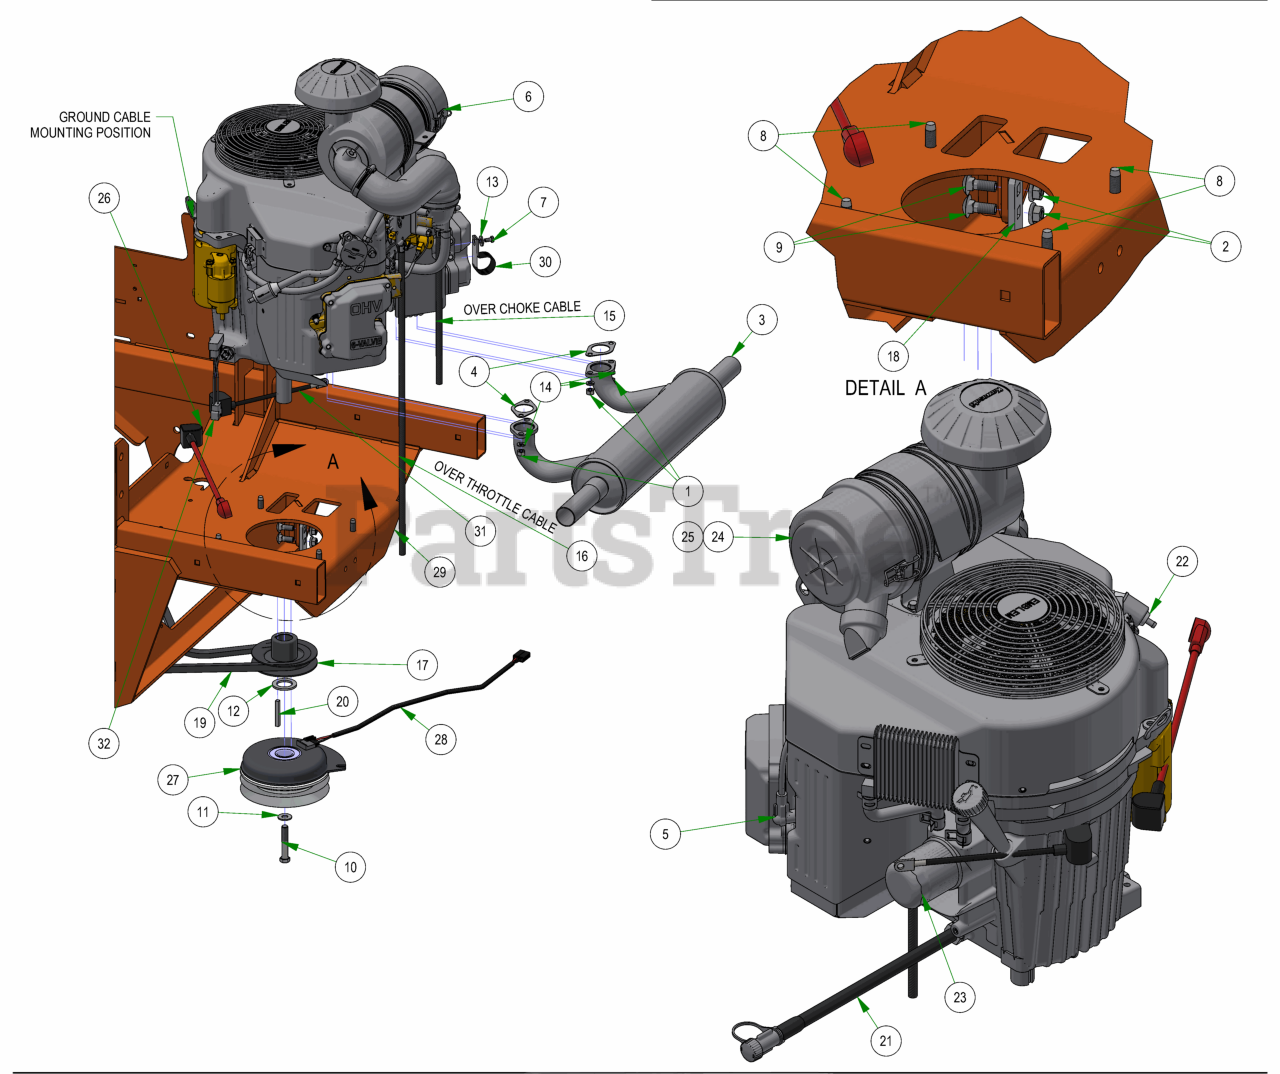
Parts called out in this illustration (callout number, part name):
1	M8-1.25 DIN 934 HEX NUT (CL.8) ZINC
2	3/8-16 NYLON INSERT FLANGE LOCKNUT (GR.F) ZINC
3	2019 Rebel/Rogue Kawasaki 1000 Muffler
4	Exhaust Gasket
5	Spark Plug - Kawasaki
6	Kawasaki FX1000 Engine
7	M6-1.0 X 12MM DIN 933 HEX TAP BOLT (CL 8.8) ZINC
8	3/8-16 X 1-1/8 HEX WASHER UNSLOT SERRATED (TRI-LOB) TRS ZINC YELLOW
9	3/8-16 X 1 CARRIAGE BOLT (GR.5) ZINC
10	7/16-20 X 2-1/2 HEX Bolt GR 8 W/ Patch
11	3/8 FLAT WASHER USS (1" OD) ZINC
12	1.140 ID X 1.750 OD X .132 THICK FLAT WASHER PLAIN
13	1/4 USS FLAT WASHER (3/4 OD) ZINC
14	5/16 SPLIT LOCKWASHER ZINC
15	Braided Heat Shielding, 12"
16	Braided Heat Shielding, 24"
17	4 3/4 Motor Pulley
18	Rebel Clutch Tab
19	2019 Rebel Pump Belt
20	1/4 X 2 SQ MACHINERY KEY 1018 STL PLAIN
21	Kawasaki Oil Drain
22	Universal Inline Fuel Filter
23	Oil Filter
24	Canister Air Filter- Outer
25	Canister Air Filter- Inner
26	14" Red Battery Cable
28	Clutch Pigtail
29	2023 Rebel Frame - Painted
30	Diesel Hydraulic Hose Clamp
31	Starter Cable
32	2019 Harness Adaptor-Gen2 FX-ALL
